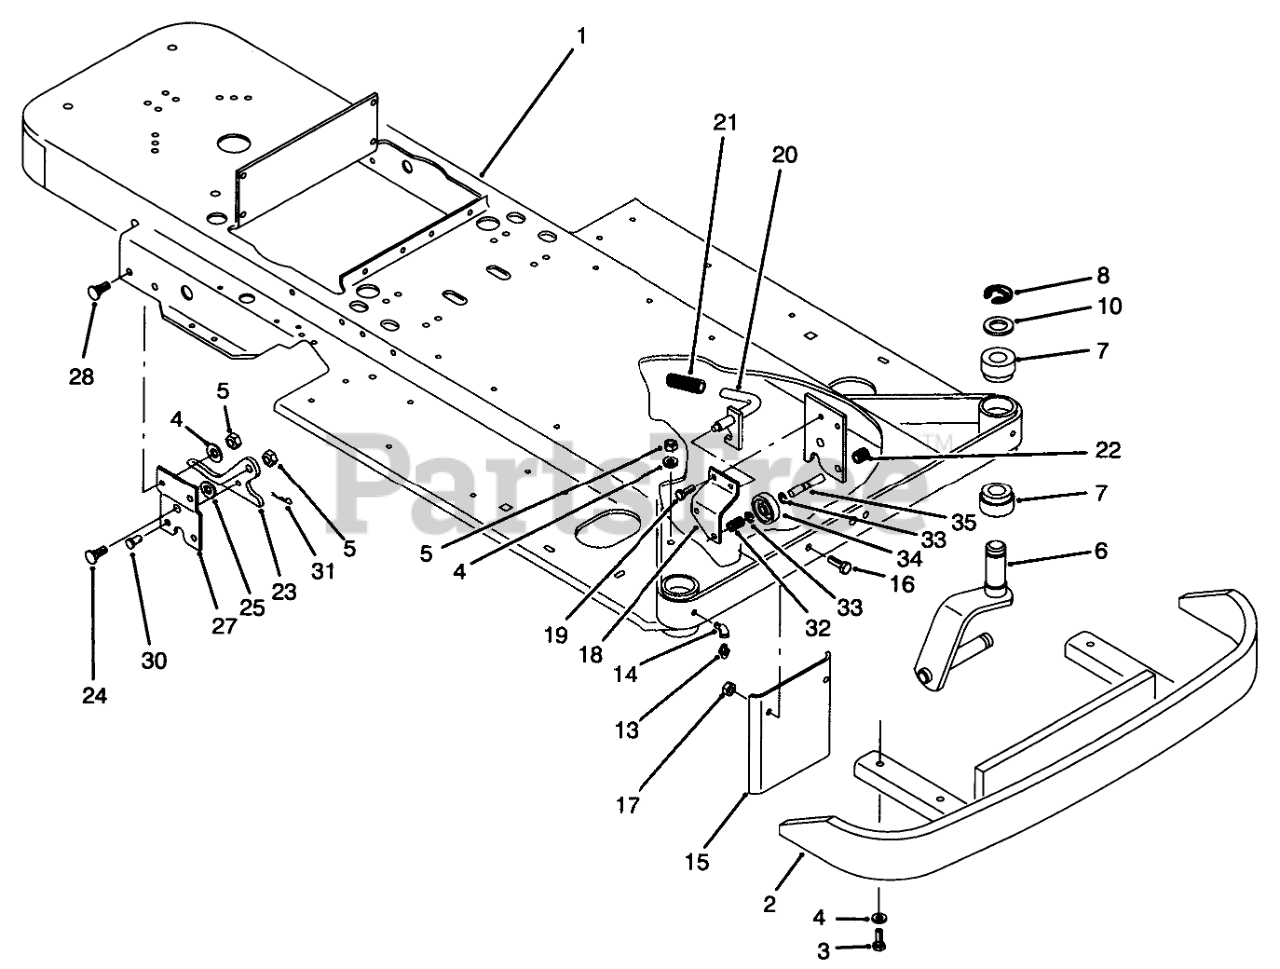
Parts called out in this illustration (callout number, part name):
1	Frame
2	Bumper-Front
3	SCREW-HH
4	WASHER-FLAT
5	NUT-LOCK, NI
6	Fork-Front Wheel, LH
7	BUSHING PIVOT
8	RING-RETAINING
11	Nut
12	DUST CAP
13	FITTING-GREASE
14	ELBOW
15	Shield
16	SCREW-HH
17	NUT-LOCK, NI
18	Bracket LH
19	SCREW-HWHTF
20	Latch LH
21	GRIP
22	CAP-ROD, PLUNGER
23	PLATE-LATCHING
24	BOLT-CARR
25	WASHER
27	Plate-Hitch
28	BOLT-CARR
30	Pin
31	Hairpin
32	SPRING
33	RING-RETAINING
35	ROD-LOCK
